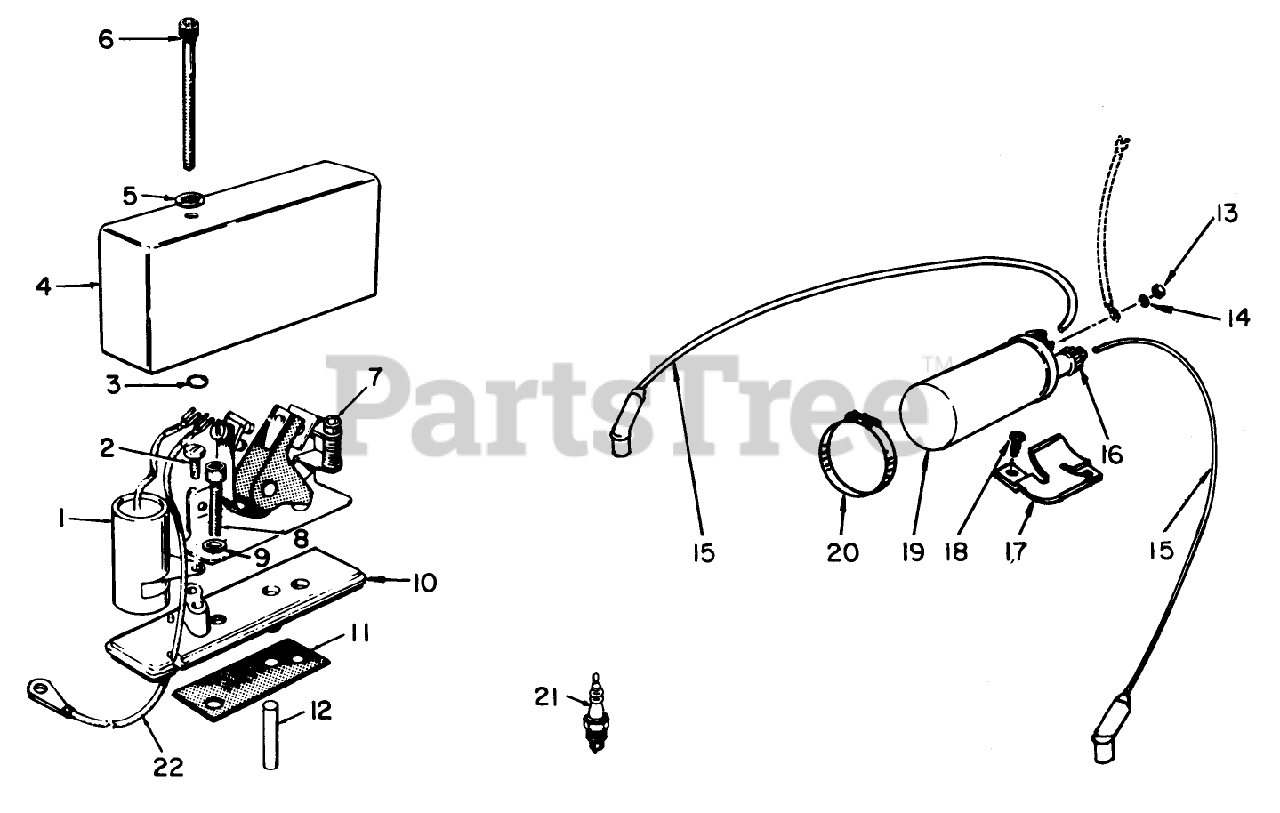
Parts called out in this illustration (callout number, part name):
1	Condenser
2	Cap Screw Slotted
3	Retainer ("O" Ring)
4	Cover, Breaker Box
5	Flat Washer
6	Screw, Cap-Hex Socket
7	Point Set Breaker
8	Cap Screw Socket Hd.
9	Lockwasher
10	Base Breaker
11	Gasket, Breaker Box
12	Plunger, Breaker Points
13	Nut-Hex, Special
14	Washer, Lock-Spring
15	Cable-Spark Plug 27" Right
16	Cap Coil Terminal
17	Bracket Ignition Coil
18	Screw, Cap Hex Washer Hd.
19	Coil, Ignition
20	Camp, Ignition Coil
21	Plug, Spark
22	Lead-Breaker Box to Coil
